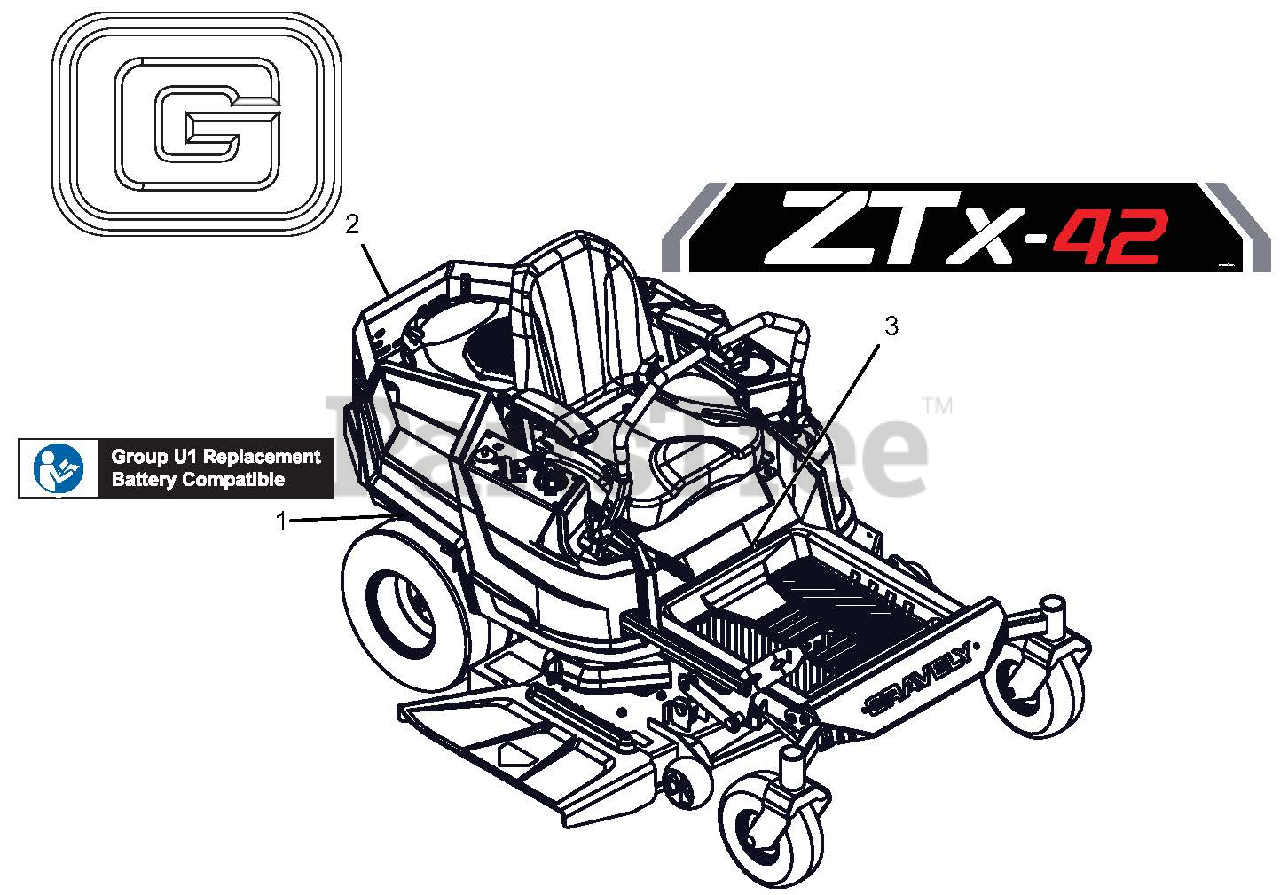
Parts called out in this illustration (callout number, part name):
1	DECAL, U1 REPLACEMENT BATTERY
2	DECAL, GRAVELY BRAND
3	DECAL, ZTX 42"
